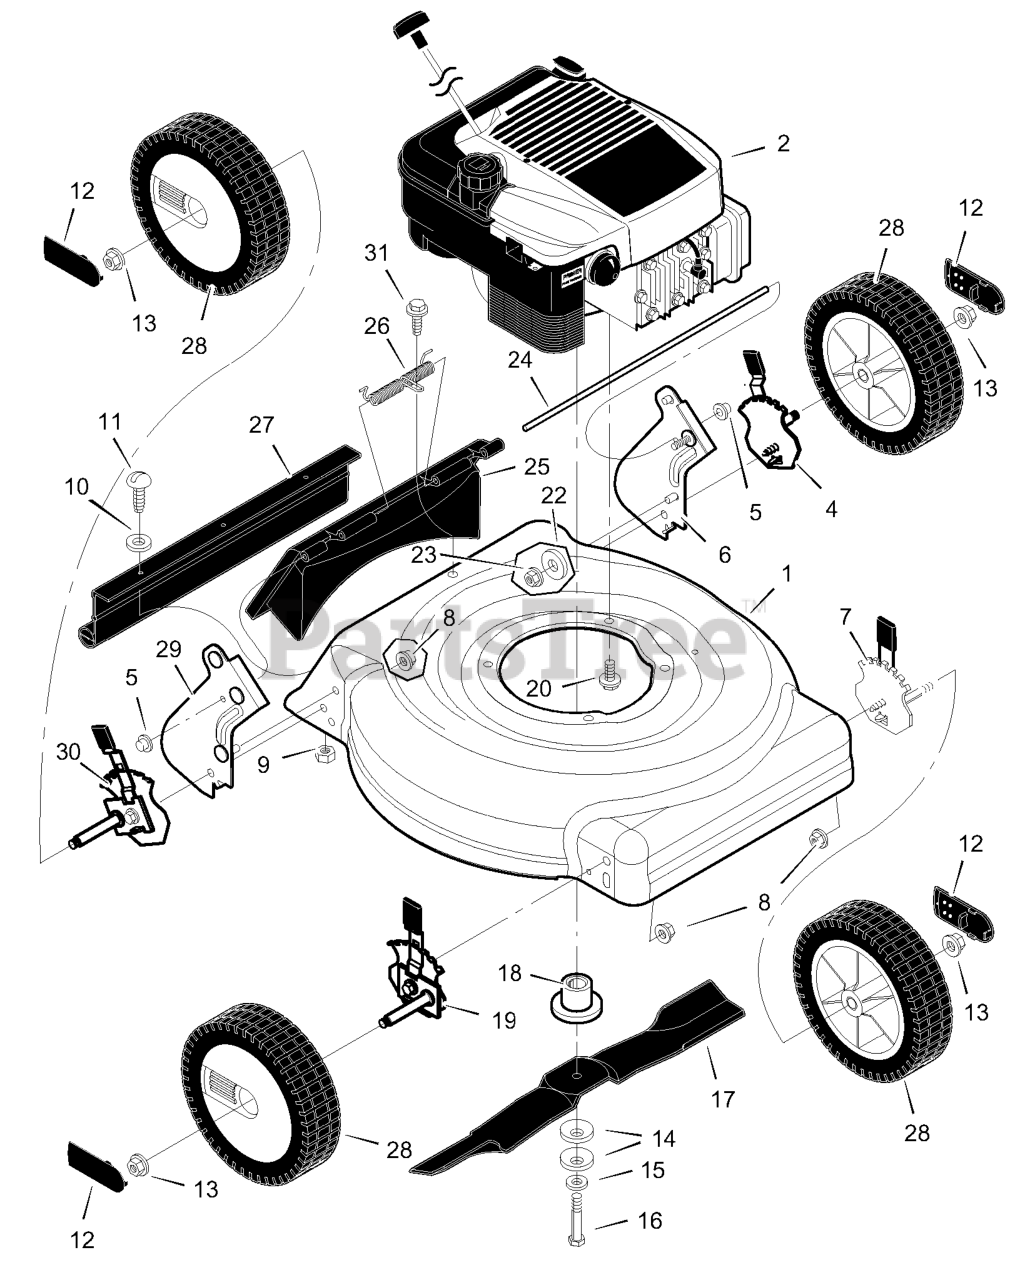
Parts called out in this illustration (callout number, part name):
1	Housing
2	Engine
4	Adjuster, Left Rear Height
5	Push On Cap
6	Bracket, Left Handle
7	Adjuster, Left Front Height
8	Nut, Flange
9	Nut, Hex
12	Hub Cap
13	Nut, Flange
14	Washer, Belleville
18	Adapter, Blade
19	Adjuster, Right Front Height
20	Bolt, Engine
22	Washer
23	Nut, Flange
24	Rod, Pivot
25	Door, Rear
27	Guard, Rear
28	Wheel
29	Bracket, Right Handle
30	Adjuster, Right Rear Height
